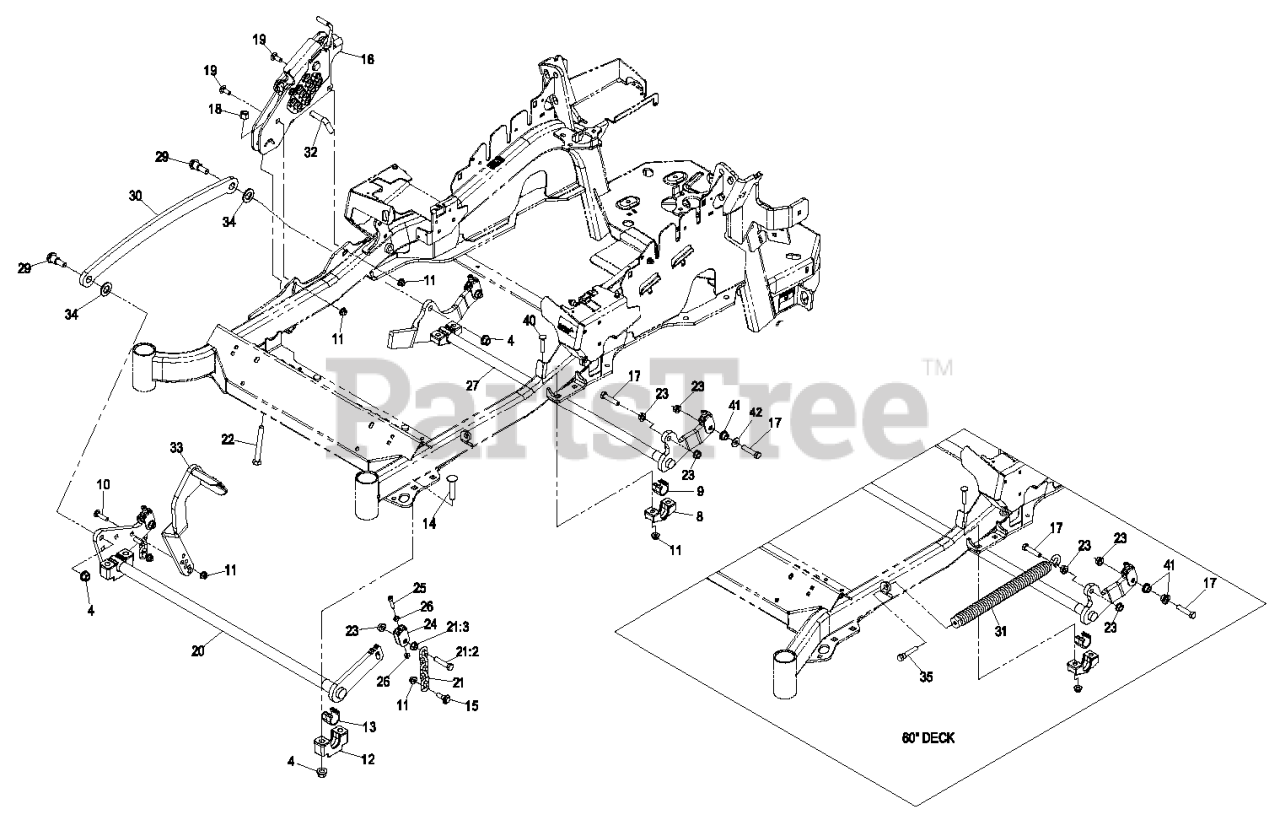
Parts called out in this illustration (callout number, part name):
4	Nut-Lock 1/2-13
9	BEARING-CROSS SHAFT, REAR
10	SCREW-CARR
11	NUT-HF, NI
12	SUPPORT-CROSS SHAFT, BEARING
13	BEARING-CROSS SHAFT, FRON
14	Bolt-Carriage 1/2-13 X 2 1/2 Spl Neck
15	SCREW-SHOULDER, HHF
16	HEIGHT-OF-CUT ASM
17	SCREW-HH
18	NUT-LOCK, NI
19	BOLT-CARR
21	Deck Lift Chain Asm
21:2	SCREW-HH
22	BOLT-TAP
24	YOKE-ADJUST, DECK
25	SCREW-HSH
26	NUT-JAM
27	LIFT-DECK, REAR
29	SCREW-SHOULDER, HHF 1/2-13 X 1.12
30	LINK-LIFT, DECK
31	SPRING-EXTENSION
32	PIN-HOC
33	FOOT LEVER
34	WASHER-FLAT
35	BOLT-SHOULDER
40	SCREW-CARR
41	BUSHING-FLANGED
42	WASHER-FLAT
43	SCREW-HH
